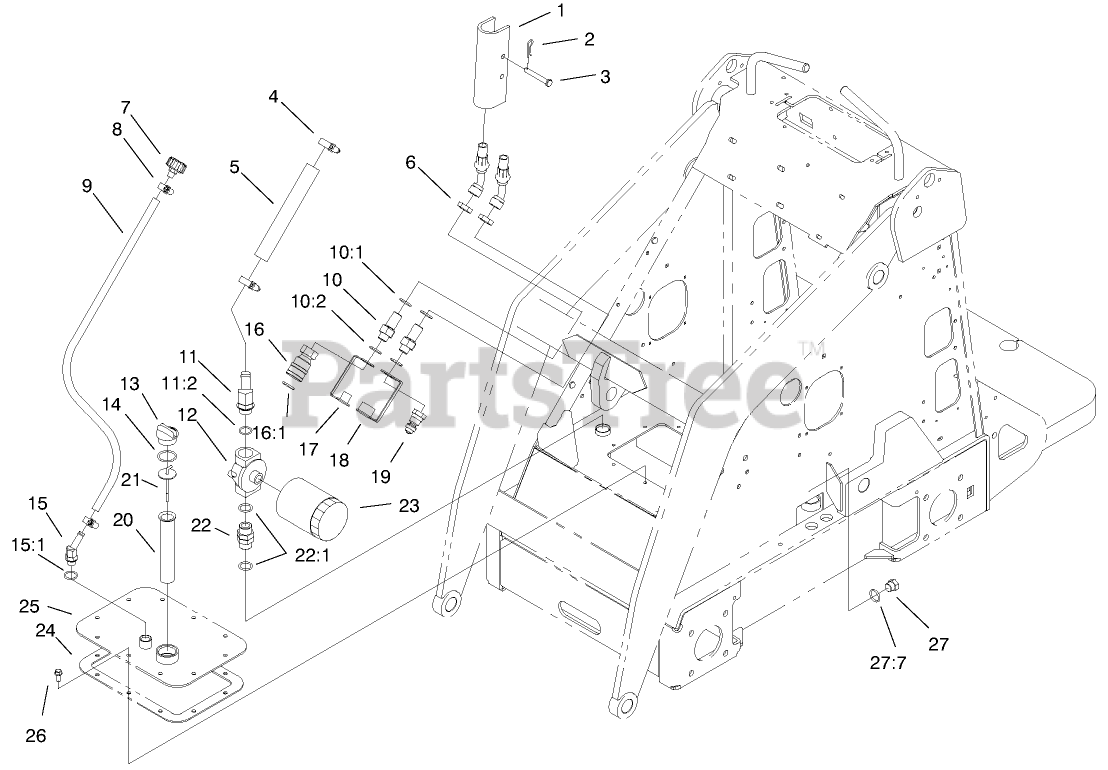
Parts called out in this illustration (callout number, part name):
1	LOCK-CYLINDER
2	PIN-HAIR
3	PIN-CLEVIS
4	CLAMP-HOSE
5	HOSE-SUCTION, HYD
6	NUT-BULKHEAD
7	BREATHER
8	CLAMP-HOSE
9	HOSE-VENT
10	UNION-BULKHEAD
10:1	O-RING
10:2	O-RING
11	FITTING-45 DEG
11:2	O-RING
12	HEAD-FILTER
13	PLUG-PLASTIC
14	O-RING
15	FITTING-HYD, 45 DEG
15:1	O-RING
16	FEMALE-DISCONNECT, QUICK
16:1	SEAL KIT
17	Dust Plug
18	Cap-Dust
19	MALE-DISCONNECT, QUICK
20	FILTER-SCREEN
21	DIPSTICK
22	FITTING-THREAD, STRAIGHT
22:1	O-RING
23	FILTER-OIL, TRANSMISSION
24	GASKET-COVER
26	SCREW
27	PLUG-HEX
27:7	O-RING
